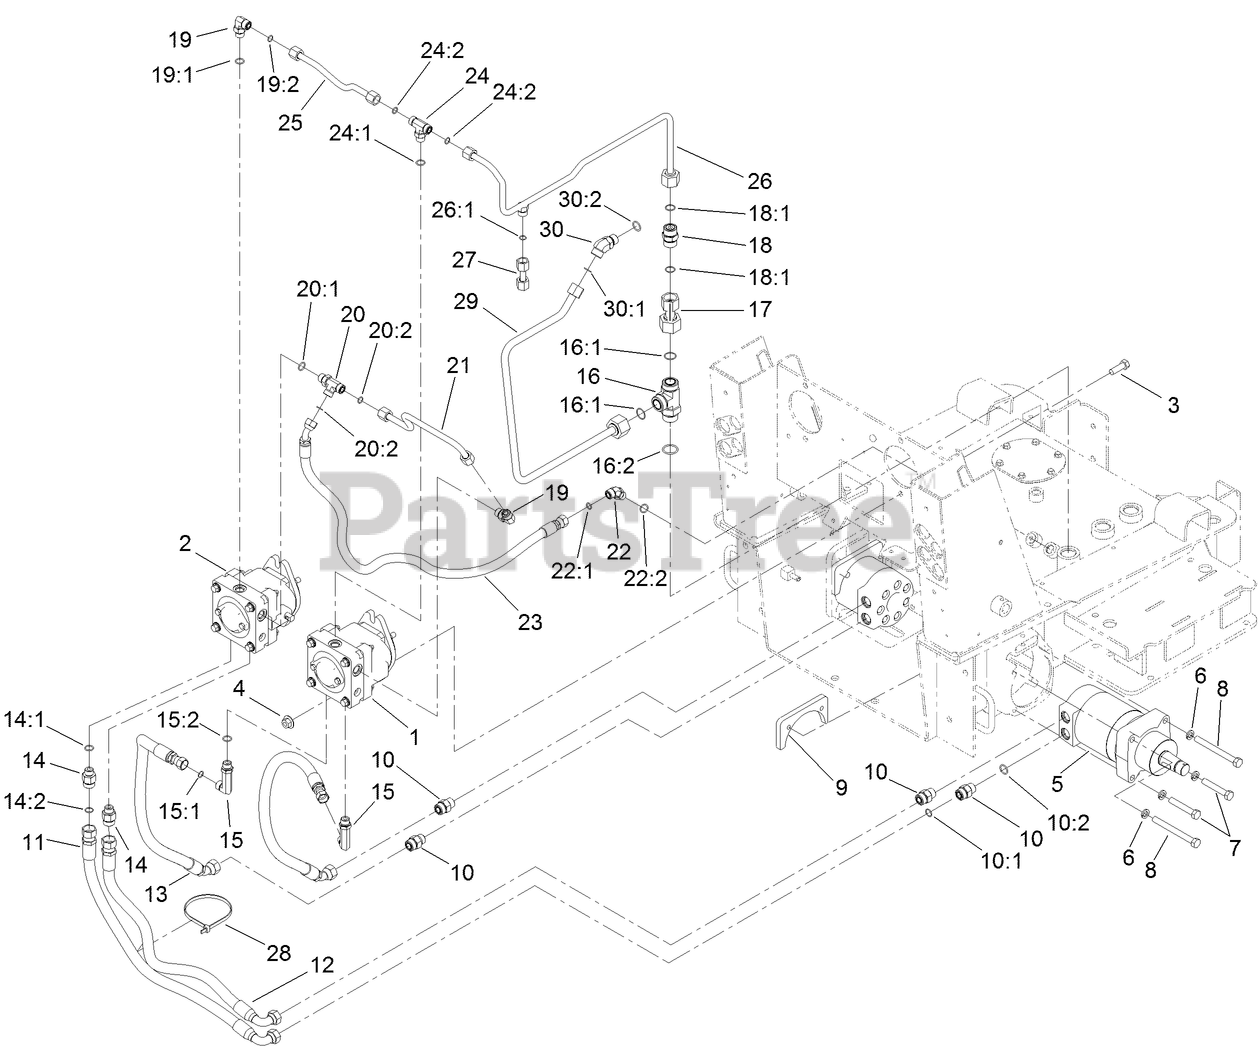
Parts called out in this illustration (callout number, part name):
1	RH HYD PUMP ASM
2	LH HYD PUMP ASM
3	SCREW-HH
4	NUT-LOCK, FLANGE
5	HYD MOTOR ASM
6	WASHER-LOCK
7	SCREW-HH, TAP
8	SCREW-HH
9	PLATE-MOUNTING
10	FITTING-STRAIGHT
10:1	O-RING
10:2	O-RING
11	HOSE-HYD
12	HOSE-HYD
13	HOSE-HYD
14	FITTING-STRAIGHT
14:1	O-RING
14:2	O-RING
15	FITTING-ELBOW 90 LONG
15:1	O-RING
15:2	O-RING
16	FITTING-TEE
16:1	O-RING
16:2	O-RING
17	TUBE-HYD
18	HYD CHECK VALVE ASM
18:1	O-RING
19	FITTING-ELBOW, 90 DEG
19:1	O-RING
19:2	O-RING
20	FITTING-TEE
20:1	O-RING
20:2	O-RING
21	TUBE-HYD
22	FITTING-HYD, 45 DEG
22:1	O-RING
22:2	O-RING
23	HOSE-HYD
24	FITTING-HYD, TEE
24:1	O-RING
24:2	O-RING
25	TUBE-HYD
26	HYD TUBE ASM
26:1	O-RING
27	TUBE-HYD
28	TIE-CABLE
29	TUBE-HYD
30	FITTING-HYD, 45 DEG
30:1	O-RING
30:2	O-RING
